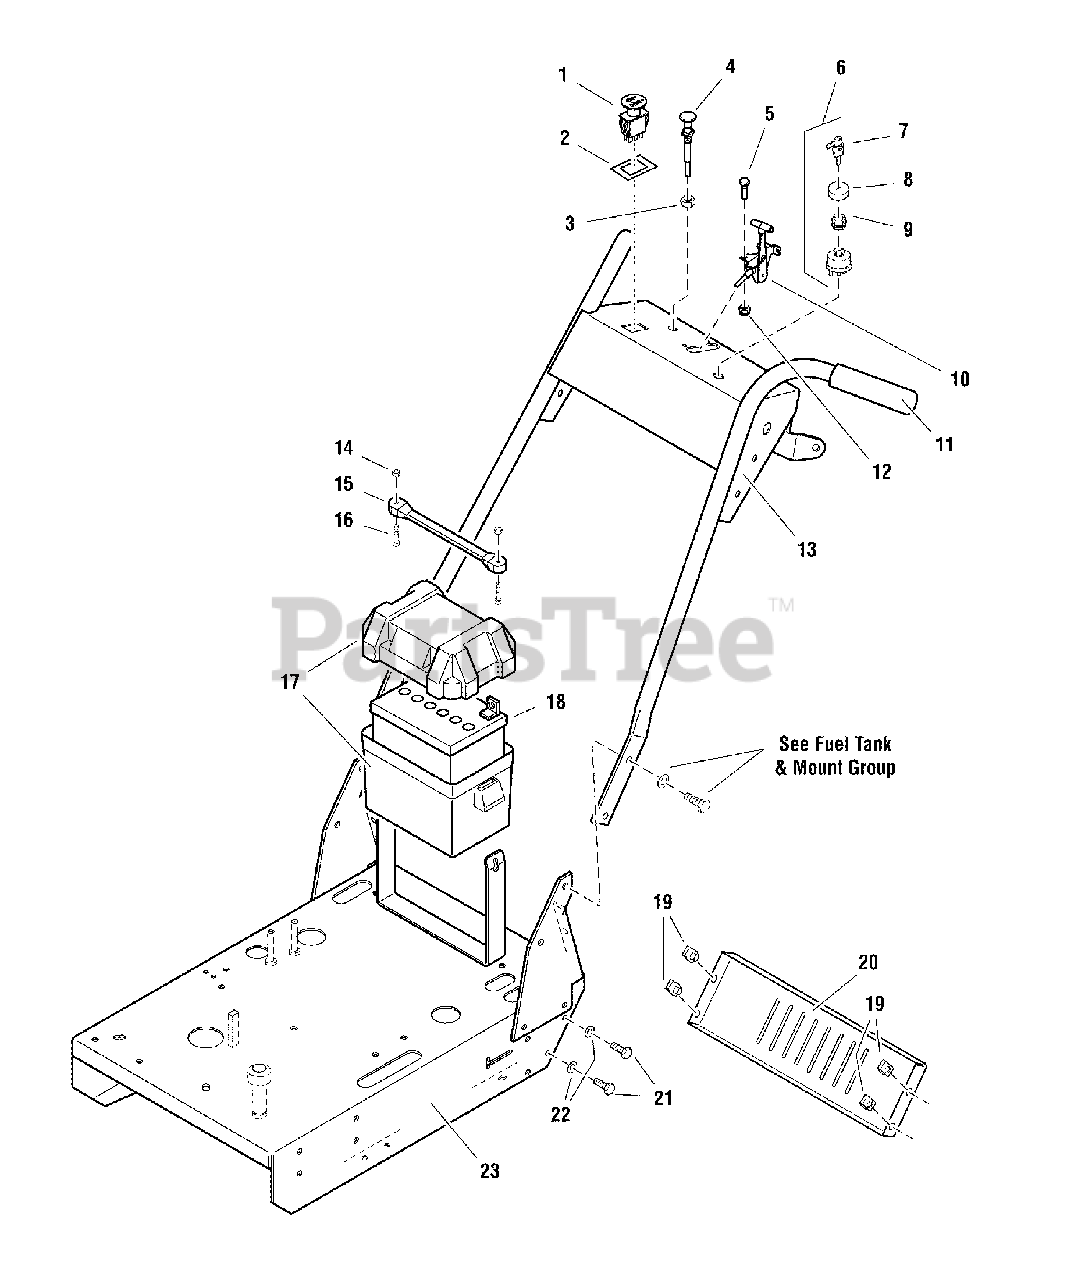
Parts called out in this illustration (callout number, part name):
1	SWITCH, BLADE ENGAGEMENT
2	RING, SWITCH RETAINER
3	NUT, 3/8-24 HEX
4	CABLE, CHOKE CONTROL, 47"
6	SWITCH, IGNITION, 6 POST
7	KEY, IGNITION MOLDED SET
8	COVER, PLASTIC, SNAP ON
9	PLASTIC NUT
10	CABLE, THROTTLE CONTROL, 48"
11	GRIP, FOAM, .940 X 5 X .187
12	NUT, 1/4-20 HEX NYLOCK FLANGE
13	WELD, HANDLE BAR, TD
14	NUT, #10-24 HEX NYLON LOCK
15	STRAP, RUBBER
16	SCREW, #10-24 X 1" RS
17	BATTERY BOX W/ DRAIN
18	BATTERY, WET ( BCIU1, 340 CCA)
19	BODY CLIP, 5/16-18 X 1/2" DEEP
20	SHIELD, REAR
21	BOLT, 5/16-18 X 1" GD5 YZ
22	WASHER, 5/16" SAE
23	WELD, ENGINE DECK, HC36
